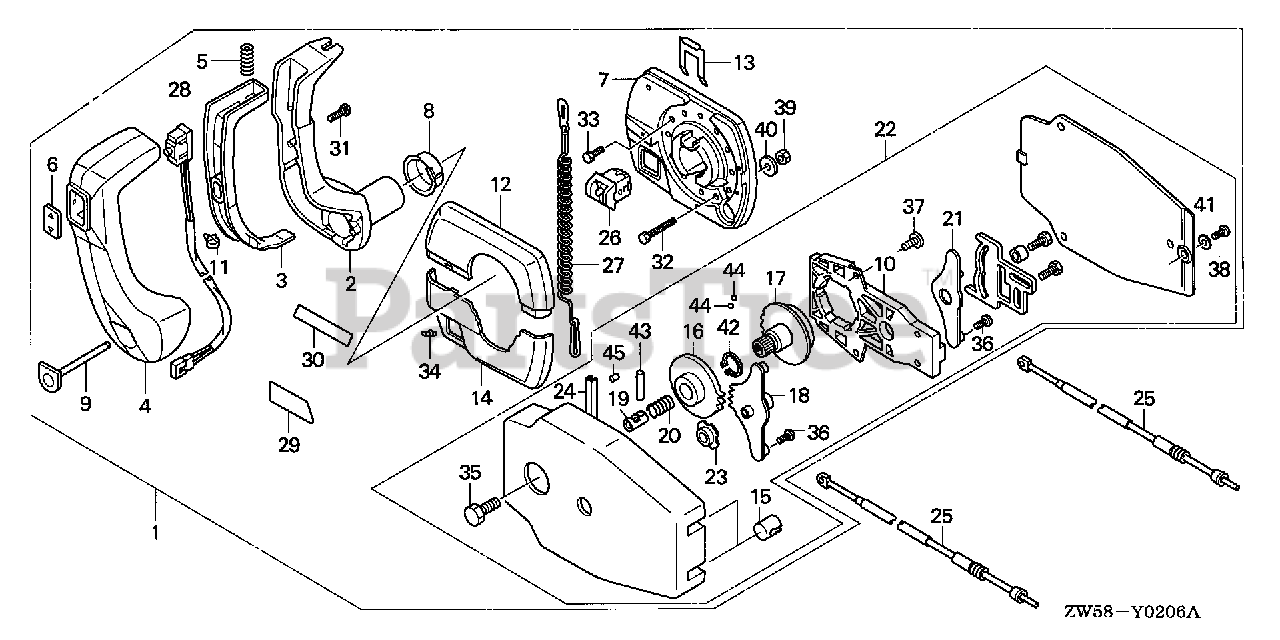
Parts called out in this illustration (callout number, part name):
1	BOX ASSY., REMOTE CONTROL (PANEL MOUNT) (NA USE ALT:06240-ZW7-U00)
2	HANDLE, REMOTE CONTROL
3	LEVER, HANDLE LOCK
4	GRIP, REMOTE CONTROL HANDLE
5	SPRING, REMOTE CONTROL HANDLE
6	COVER, GRIP
7	HOUSING ASSY., REMOTE CONTROL BOX (A)
8	BUSHING
9	BUTTON, THROTTLE
10	FRAME ASSY., REMOTE CONTROL BOX
11	BAND B, CABLE
12	HOUSING, REMOTE CONTROL BOX (B)
13	RETAINER
14	HOUSING, REMOTE CONTROL BOX (C)
15	GROMMET
16	WHEEL, CONTROL
17	SHAFT, HANDLE (NOT AVAILABLE)
18	ARM ASSY., SHIFT LINK
19	SHAFT, GEARSHIFT
20	SPRING, GEARSHIFT
21	ARM ASSY., THROTTLE LINK
22	HOUSING ASSY. (INNER) (PANEL MOUNT)
23	BUSH
24	SPRING
25	CABLE, REMOTE CONTROL (10'') (BRUNSWICK)
25	CABLE, REMOTE CONTROL (11'') (BRUNSWICK) (NOT AVAILABLE)
25	CABLE, REMOTE CONTROL (12'') (BRUNSWICK) (NOT AVAILABLE)
25	CABLE, REMOTE CONTROL (13'') (BRUNSWICK) (NOT AVAILABLE)
25	CABLE, REMOTE CONTROL (14'') (BRUNSWICK) (NOT AVAILABLE)
25	CABLE, REMOTE CONTROL (15'') (BRUNSWICK) (NOT AVAILABLE)
25	CABLE, REMOTE CONTROL (16'') (BRUNSWICK) (NOT AVAILABLE)
25	CABLE, REMOTE CONTROL (17'') (BRUNSWICK) (NOT AVAILABLE)
25	CABLE, REMOTE CONTROL (18'') (BRUNSWICK) (NOT AVAILABLE)
25	CABLE, REMOTE CONTROL (19'') (BRUNSWICK) (NOT AVAILABLE)
25	CABLE, REMOTE CONTROL (20') (BRUNSWICK) (NOT AVAILABLE) (ALT. PNO: 24920-ZW1-003AH)
26	SWITCH ASSY., EMERGENCY STOP
27	WIRE, EMERGENCY
28	SWITCH ASSY., POWER TRIM-TILT (A)
29	MARK, REMOTE CONTROL (A)(PANEL)
30	MARK, REMOTE CONTROL (B)(FOR STARBOARD)
30	MARK, REMOTE CONTROL (C)(FOR PORT)
31	SCREW A (NOT AVAILABLE)
32	SCREW B
33	SCREW C
34	SCREW SET (1/4-20X16")
35	BOLT
36	SCREW (8-32X3/8)
37	SCREW (10-32X5/8)
38	SCREW (10-32X5/8)
39	NUT (1/4X20)
40	WASHER
41	WASHER
42	CIRCLIP (OUTER)
43	PIN, GEARSHIFT
44	BALL, STEEL
45	ROLLER, SHIFT CLICK
